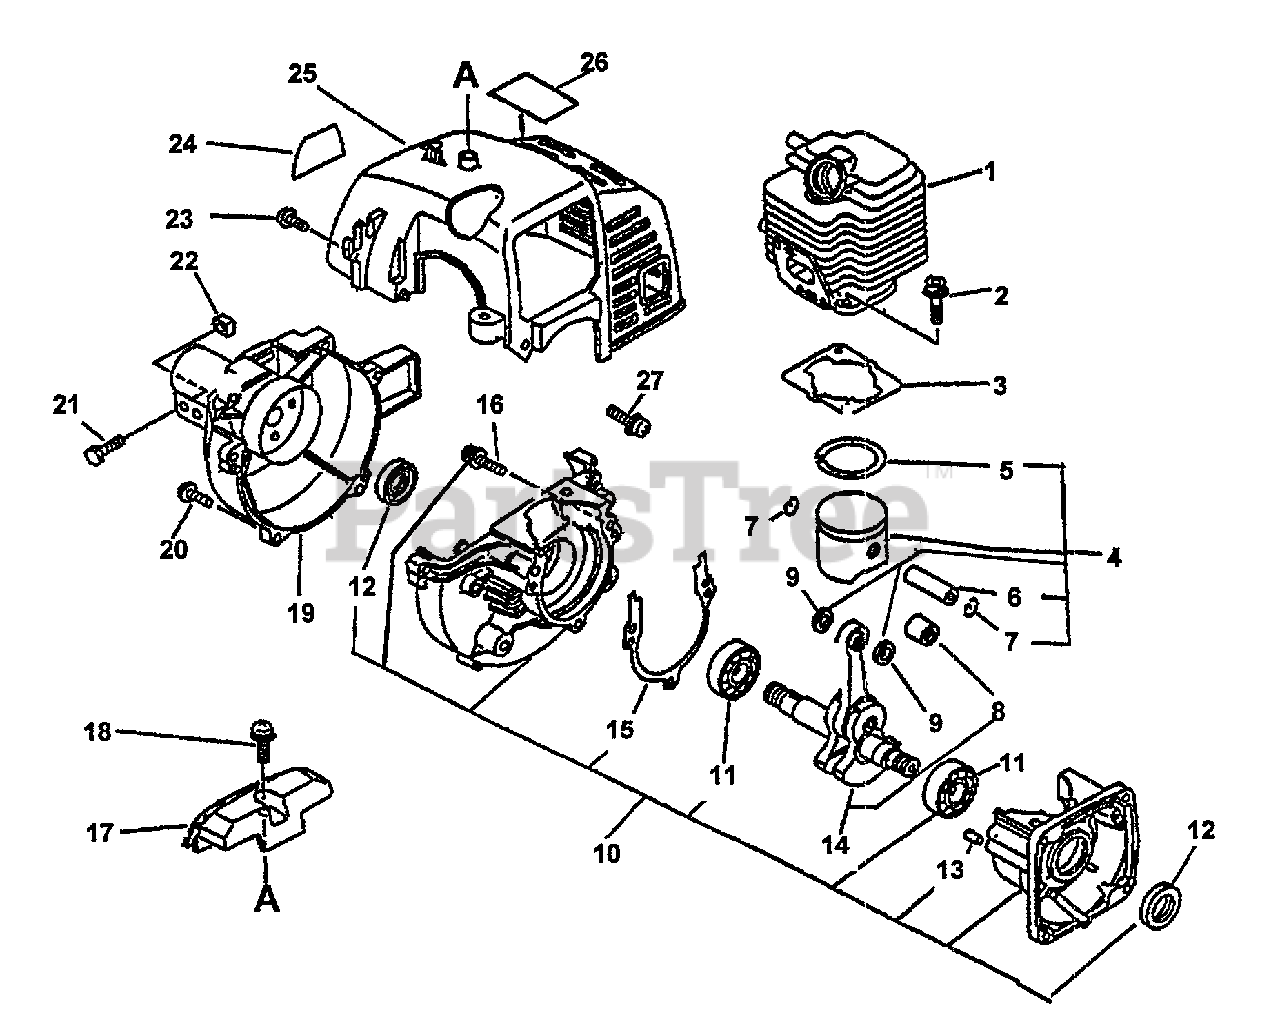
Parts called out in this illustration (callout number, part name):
1	CYLINDER
2	SCREW - 5X22
3	GASKET, CYLINDER
4	PISTON KIT
5	RING, PISTON
6	PIN, PISTON
7	RING, RETAINING
8	BEARING, NEEDLE
9	SPACER, PISTON
10	CRANKCASE KIT
11	BEARING, BALL - 6201
12	SEAL, OIL
13	PIN - LOCATING
14	CRANKSHAFT ASSY
15	GASKET, CRANKCASE
16	SCREW - 5X28
17	GUARD, TOP - GRAY
18	SCREW - 5X16 -- TAPPING
19	FAN CASE ASSY
20	SCREW - 4X22
21	BOLT - 5X28
22	NUT - 5 -- SQUARE
23	SCREW - 4X16
24	LABEL - MODEL
25	COVER, ENGINE - GRAY
26	LABEL - HOT SURFACE
27	SCREW - 4X12 -- TAPPING
